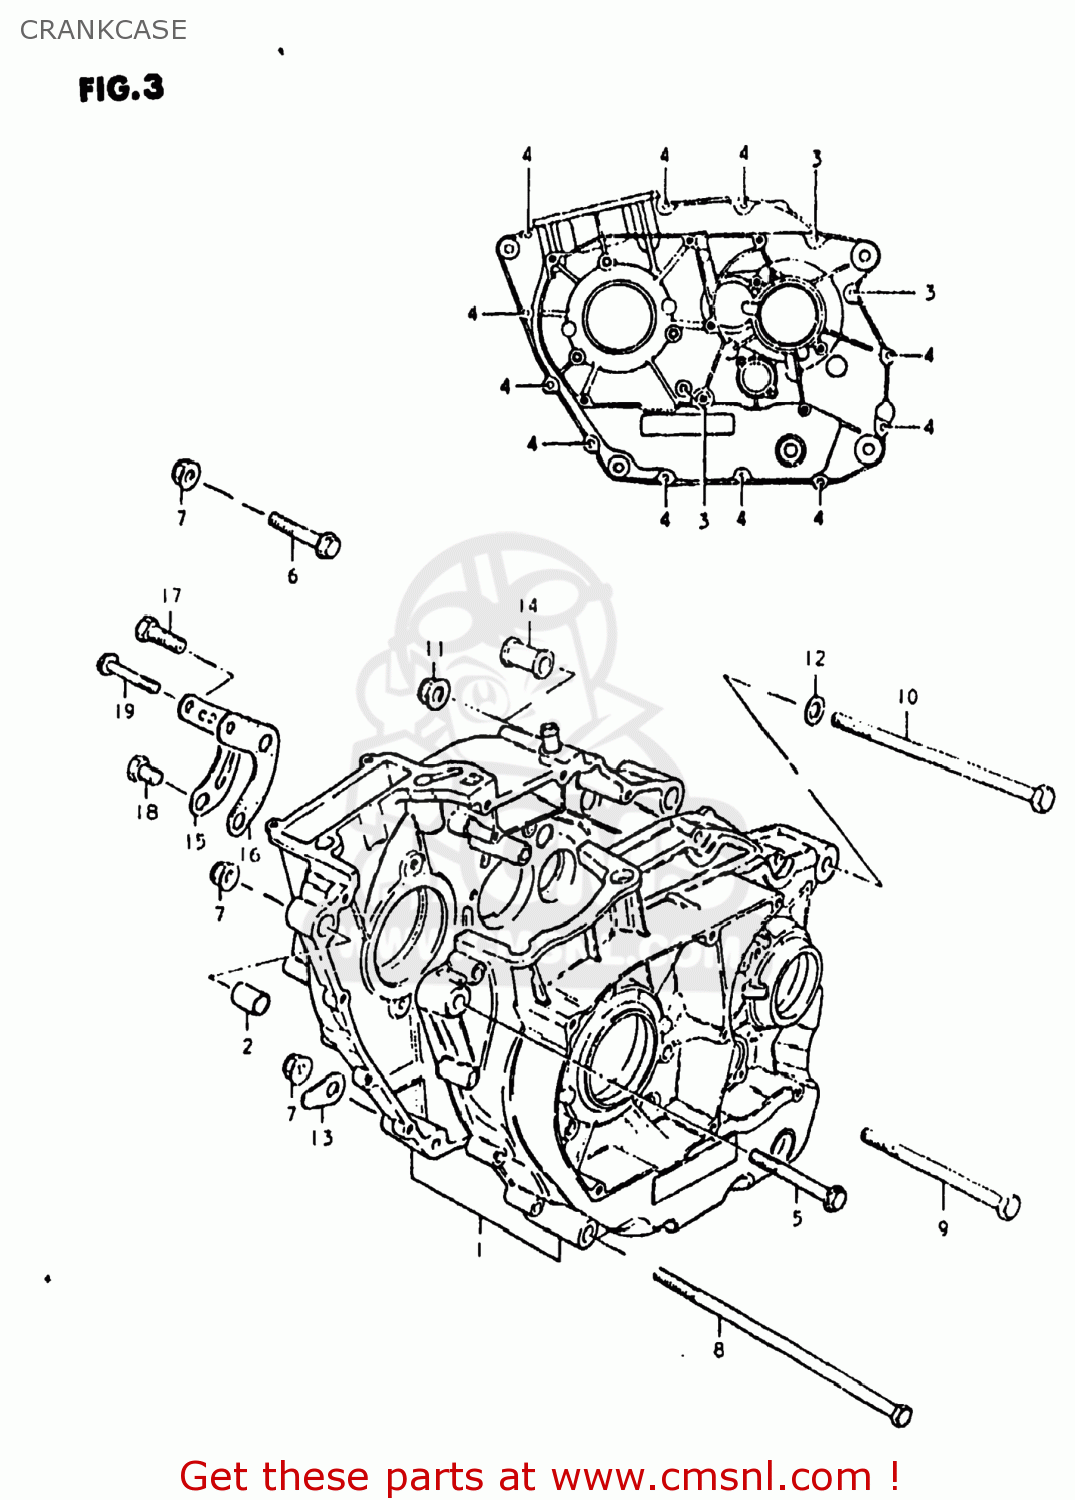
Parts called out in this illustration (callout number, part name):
1	CRANKCASE SET
2	PIN
3	SCREW
4	SCREW (6X35)
5	BOLT (8X70)
6	BOLT
7	NUT
8	BOLT(10X190)
9	BOLT 10X115
10	BOLT 10X155
11	NUT
12	WASHER
13	WASHER
14	SPACER
15	CAP,OIL GALLERY
16	GASKET,OIL GALLERY (MCA)
17	BOLT,UNION
18	PLUG
19	BOLT
